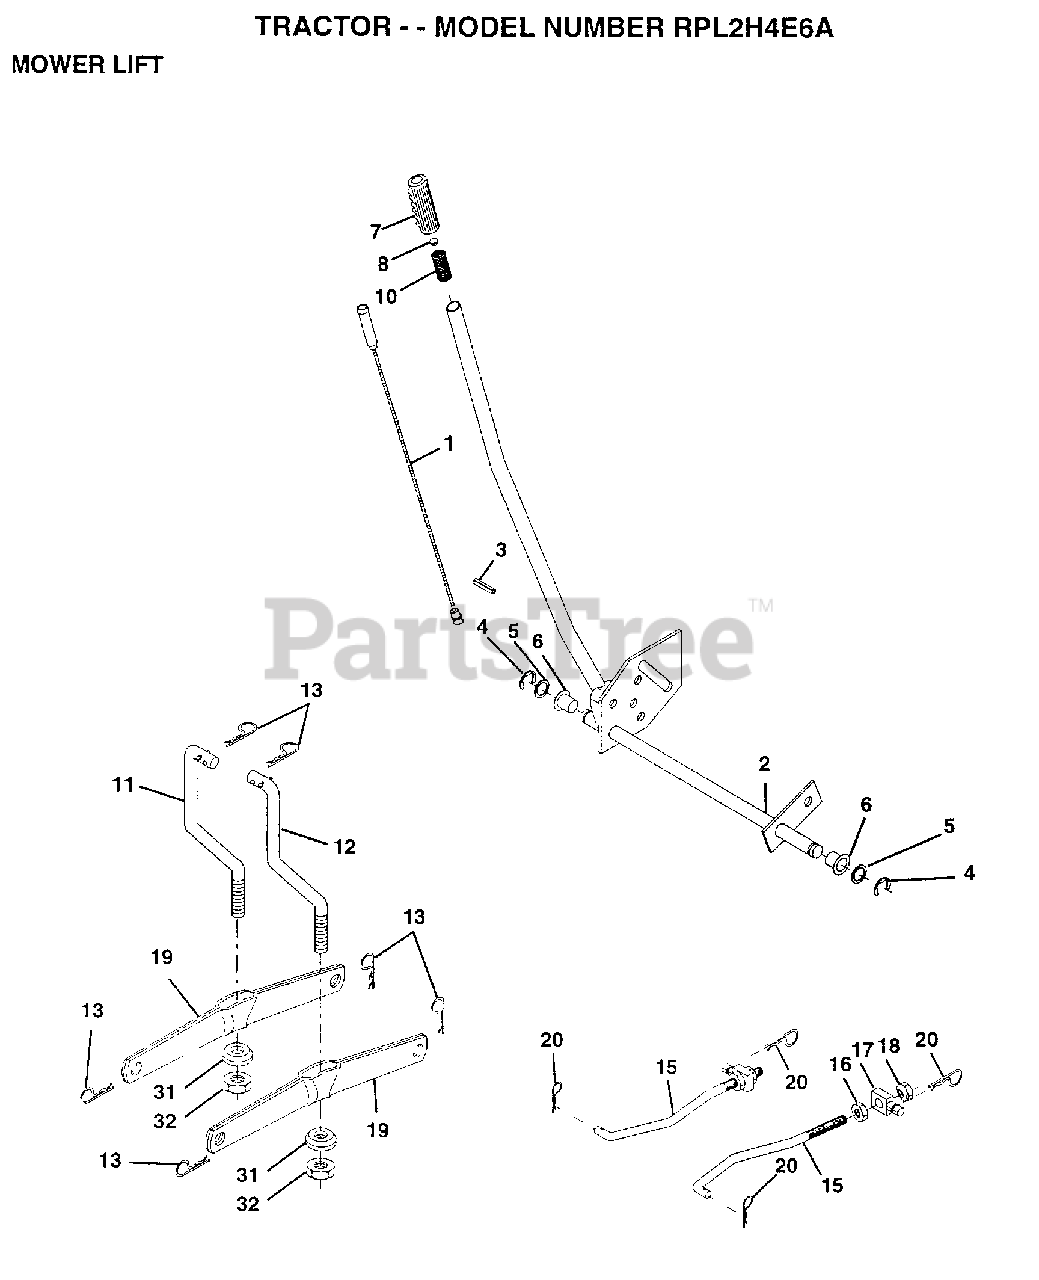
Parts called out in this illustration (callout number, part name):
1	WIRE ASM
2	HANDLE.LIFT.LH.
3	PIN GROOVE
5	WASHER
6	NYLON BEARING
7	GRIP
15	LINK.FRONT
16	NUT
17	TRUNION
18	NUT.LK.W/WSH.1/2.
19	ARM SUSP REAR
20	RETAINER.SPRING
31	BEARING PVT LH
32	NUT.CROWNLOCK.3/8
